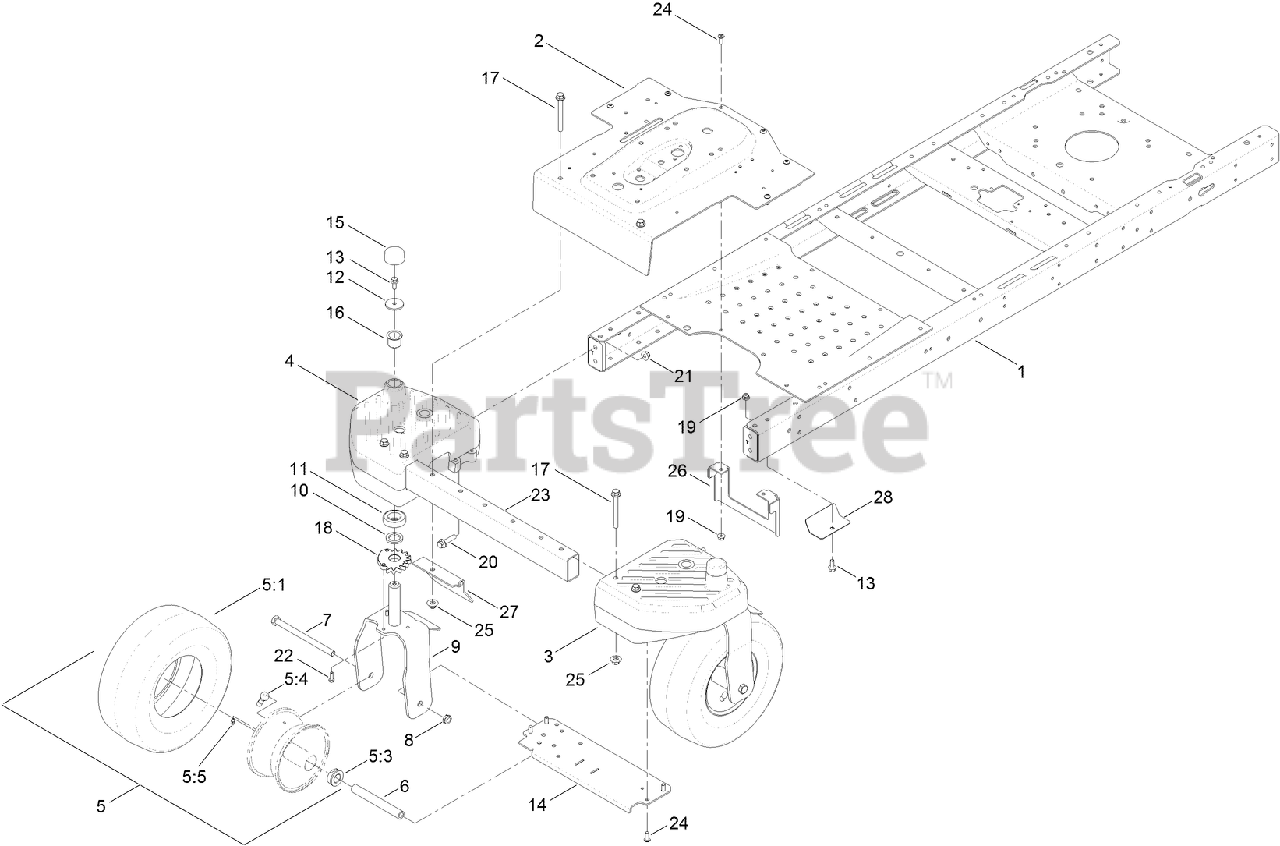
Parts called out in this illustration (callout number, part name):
1	FRAME ASM
2	PAN-STEER, FRONT
3	HOUSING-SPINDLE, LH
4	HOUSING-SPINDLE, RH
5	13 INCH WHEEL AND TIRE ASM
5:1	TIRE-13 INCH
5:3	BUSHING-FLANGE
5:5	FITTING-GREASE
6	SPANNER
7	SCREW-HH
8	NUT-HEX
9	CASTER FORK ASM
10	WASHER-THRUST
11	BEARING-BALL
12	WASHER-FLAT
13	SCREW-HHF
14	PLATE-BRIDGE, NARROW
15	CAP-CASTER
16	BUSHING-PIVOT
17	SCREW-HHF
18	GEAR-WHEEL, 15 TOOTH
19	NUT-HF, NI
20	SCREW-HHF
21	NUT-HF, NI
22	SCREW-HH
23	TUBE-FRONT, NARROW
24	SCREW-HSBH
25	NUT-FLANGE, NI
26	BRACKET-UPSTOP
27	GUARD-FRONT
28	PLATE-GUARD
